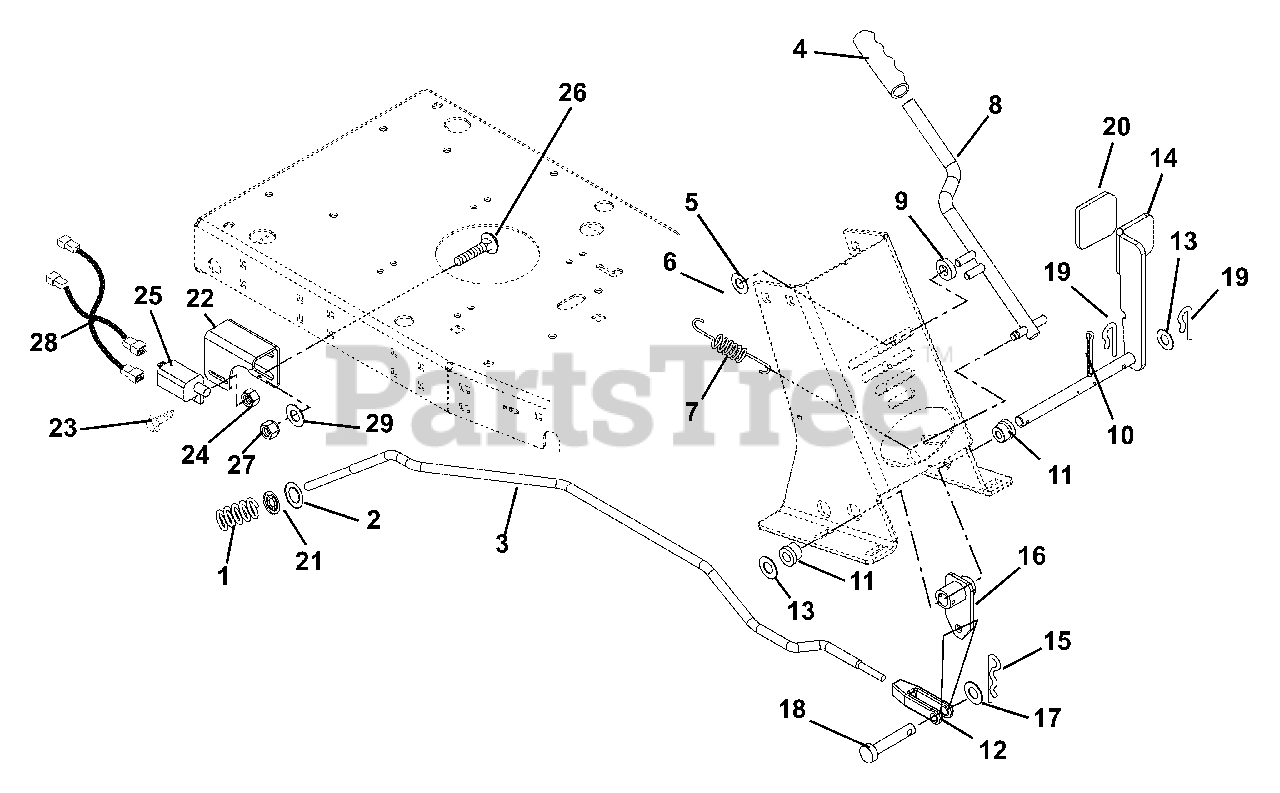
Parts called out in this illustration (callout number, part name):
1	Spring, Compression .080 x .52 x 2.90
2	Washer, Flat Steel .33 x 2.125 x .098
3	Rod, Brake
5	Washer, Flat Steel .38 x .875 x .083
6	Nut, Locking Top Flange .38-16
7	Spring, Tension .048 x .44 x 2.12
8	Weldment, Parking Brake
9	Bushing, Flange .406 x .88 x .27 x .140 Grade 2
10	Pin, Cotter .12 x 1.00 Extended Prong Square Cut
11	Bushing, Flange .515 x .75 x .745 x 1.00 Nylon
12	Yoke, .312-24 x 2.25
13	Washer, Flat Steel .505 x 1.00 x .062
14	Weldment, Brake Pedal
15	Pin, Hair
16	Brake Rod Arm and Hub
17	Washer, Flat Steel .38 x .87 x .179
18	Pin, Clevis .312 x .822
19	Clip, Spring
20	Grip, Pedal
21	Nut-Push .312
22	Bracket, Switch Mount
23	Screw, Machine 10-24 x .75 Hex Washer Head
24	Nut, Locking Nylon 10-24 with Insert
25	Switch, Single Pole (N.O.)
26	Bolt, Round Head Square Neck .38-16 x 1.00 Grade 5
27	Nut, Locking Nylon .38-16
28	Jumper, Harness
29	Washer, Flat Steel .406 x .812 x .065
